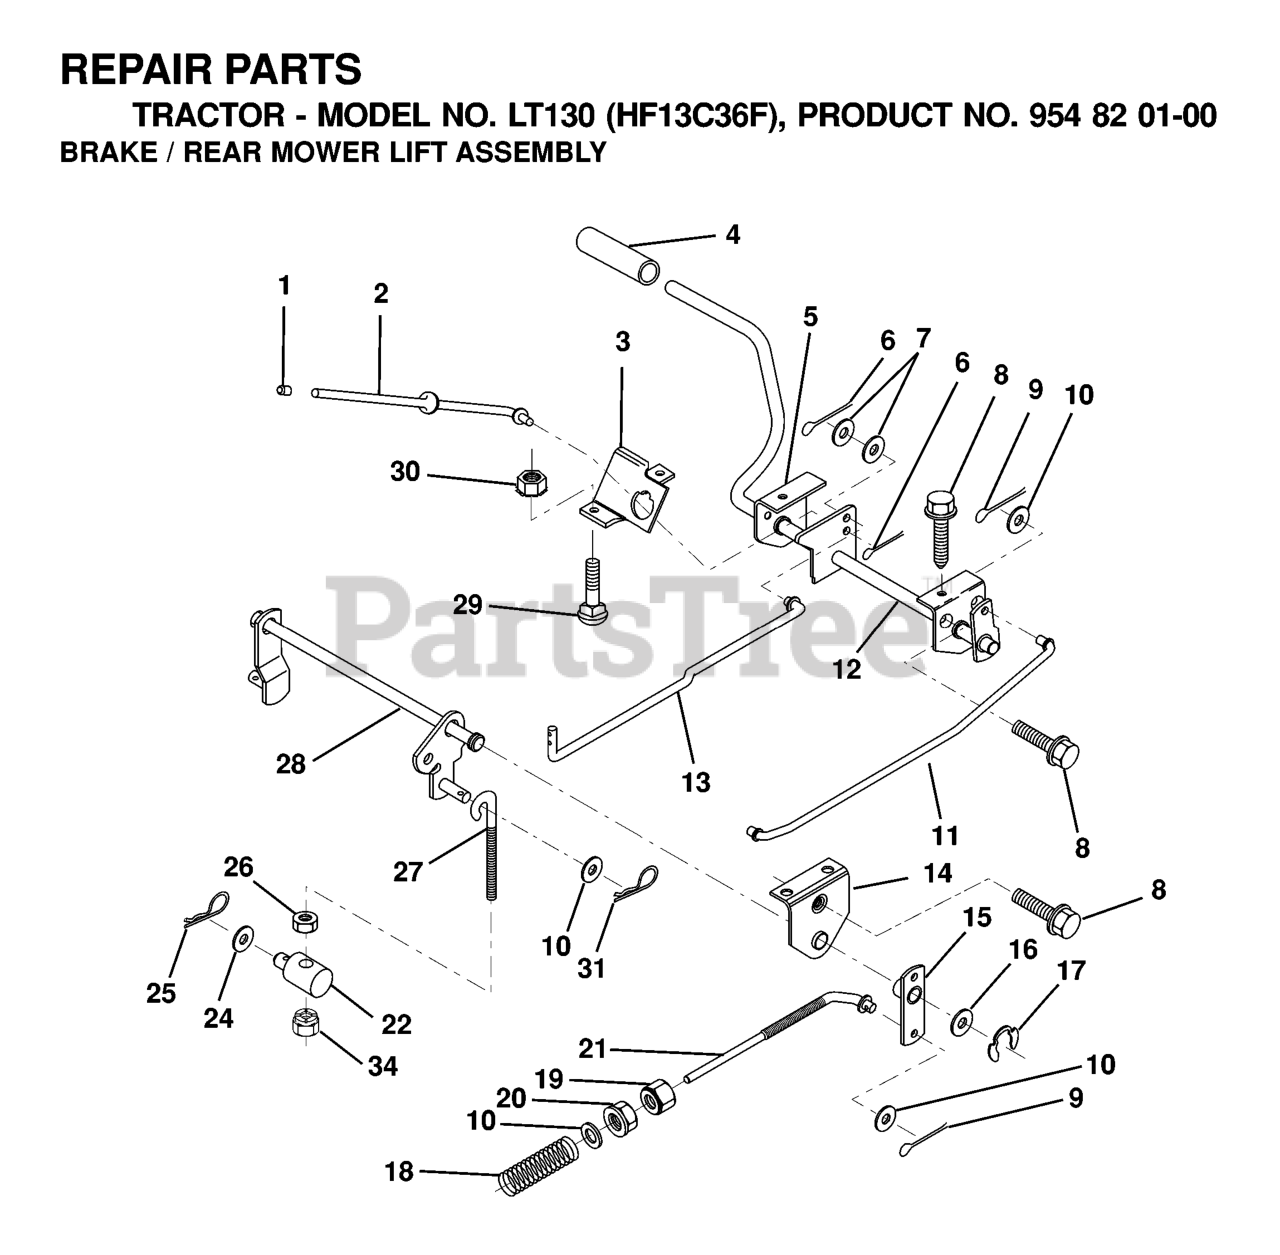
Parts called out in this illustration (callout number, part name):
1	PLUNGER CAP
2	ROD,PARK BRAKE
3	BRKT,PARK BRAKE
4	FOOT PEDAL COVER
5	BRKT,CLU PEDAL LH
6	COTTER PIN
8	Screw 5/16-18 x 1/2 Hex, Self Tapping 5/16-18 x 1/2
9	COTTER PIN
10	WASHER
11	ROD,FRT BRAKE
12	CLUTCH/BRAKE PEDAL ASSY
13	ROD,CLUTCH
14	BRKT,LIFT SHAFT
15	ARM, BRAKE ASMBLY
17	Ring, Klip Truarc #5304-75
18	SPRING, BRAKE ROD
19	NUT
20	NUT
21	ROD REAR BRAKE
22	TRUNNION, LEFT
24	WASHER
25	SPRING TI
26	LOCKNUT
27	LINK.MOWER.REAR
28	REAR MOWER LIFT ASSY
29	BOLT.CARR.SQNK.5/16-18UNC.X3/4
30	NUT
31	SPRING RETAINER
